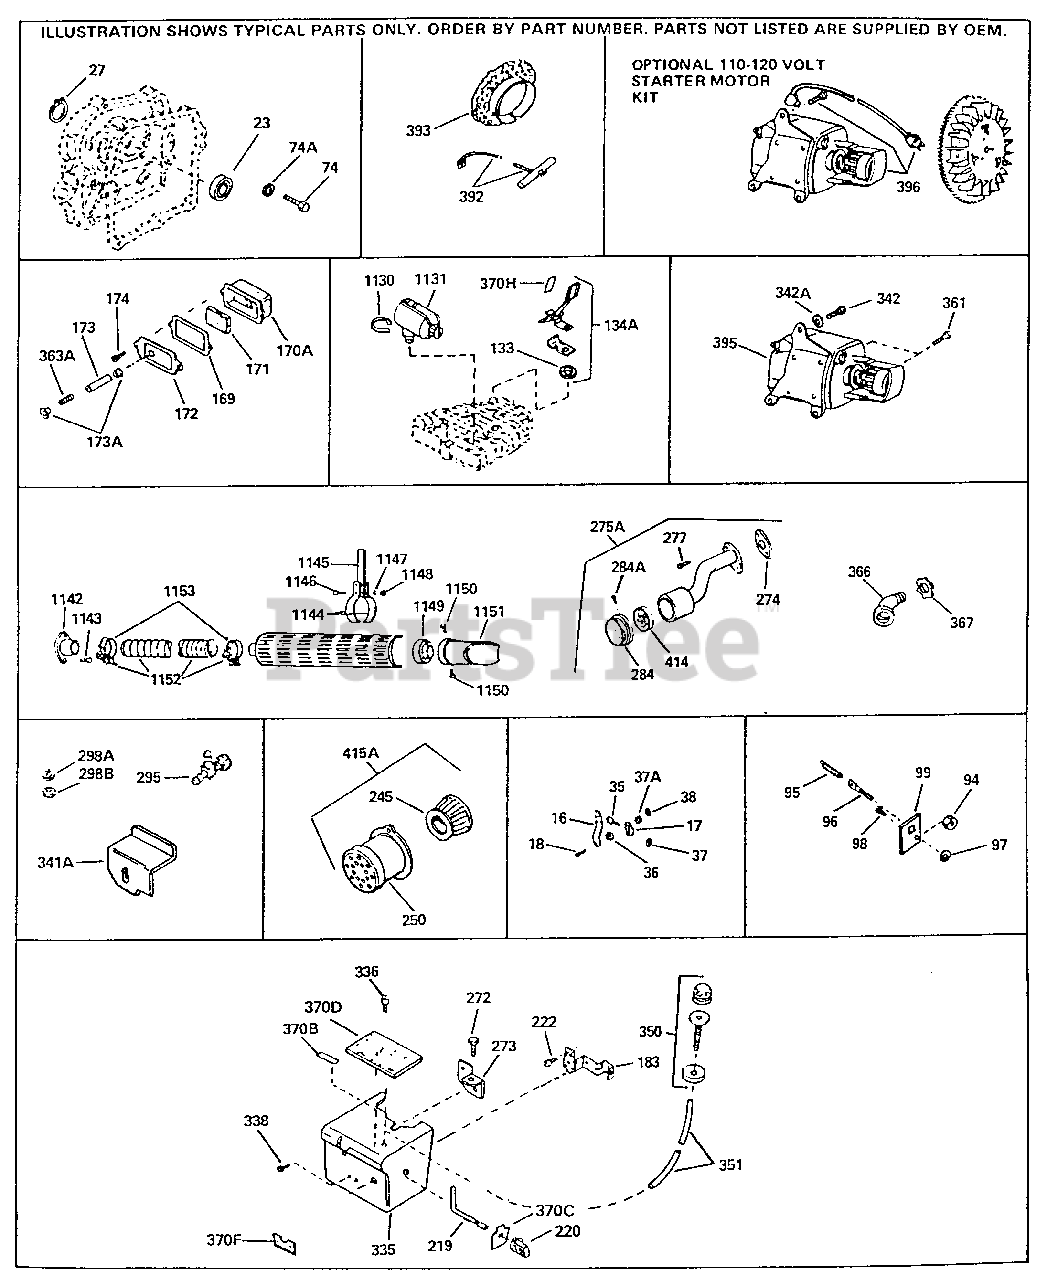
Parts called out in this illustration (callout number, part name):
16	Lever, Governor
17	Governor Lever Clamp
18	Screw, 8-32 x 5/16"
35	Screw, 10-32 x 3/4"
36	Lock Washer #8
37	Lock Nut, 10-32
37A	Lock Nut, 8-32
38	Retaining Ring
133	Lockwasher, 5/16
171	Element, Valve body
174	Screw, 10-24 x 1/2"
245	Air Filter (Paper) also available in Packaged Part #740029B
250	Body, Air cleaner
272	Screw, 10-24 x 3/8"
274	* Gasket, Exhaust
275A	Muffler Incl. 274, 277, 284, 284A & 4 14
277	Screw, 1/4-20 x 2-1/2" Use as requir ed
277	Screw, 1/4-20 x 5/8" Use as required
277	Screw, 1/4-20 x 2-3/8" Use as requir ed
277	Screw, 1/4-20 x 2-1/4" Use as requir ed
284	Cover, Muffler (Use as required)
284A	Screw, 8-18 x 3/8" (Use as required)
342	Screw, T-30, 1/4-20 x 1/2" as req.)
342	Screw, 1/4-20 x 5/8" Use as required
342	Screw, 1/4-20 x 7/16" Use as require d
342	Screw, 1/4-20 x 11/16" Use as requir ed
342A	Washer (Use as required)
396	Starter Motor kit (110-120 Volt) (opt ional) This 120-Volt starter motor kit may be added to this engine if cy linder has drilled and tapped starter mounting bosses and a ring gear flyw heel.Refer to the service numberstamp ed on end cap of motor or
414	Muffler Screen (Use as required)
415A	Air Cleaner Ass'y. (Incl. 233, 238, 2 39, 243, 245, 250 & 370G) (Use as req uired)
